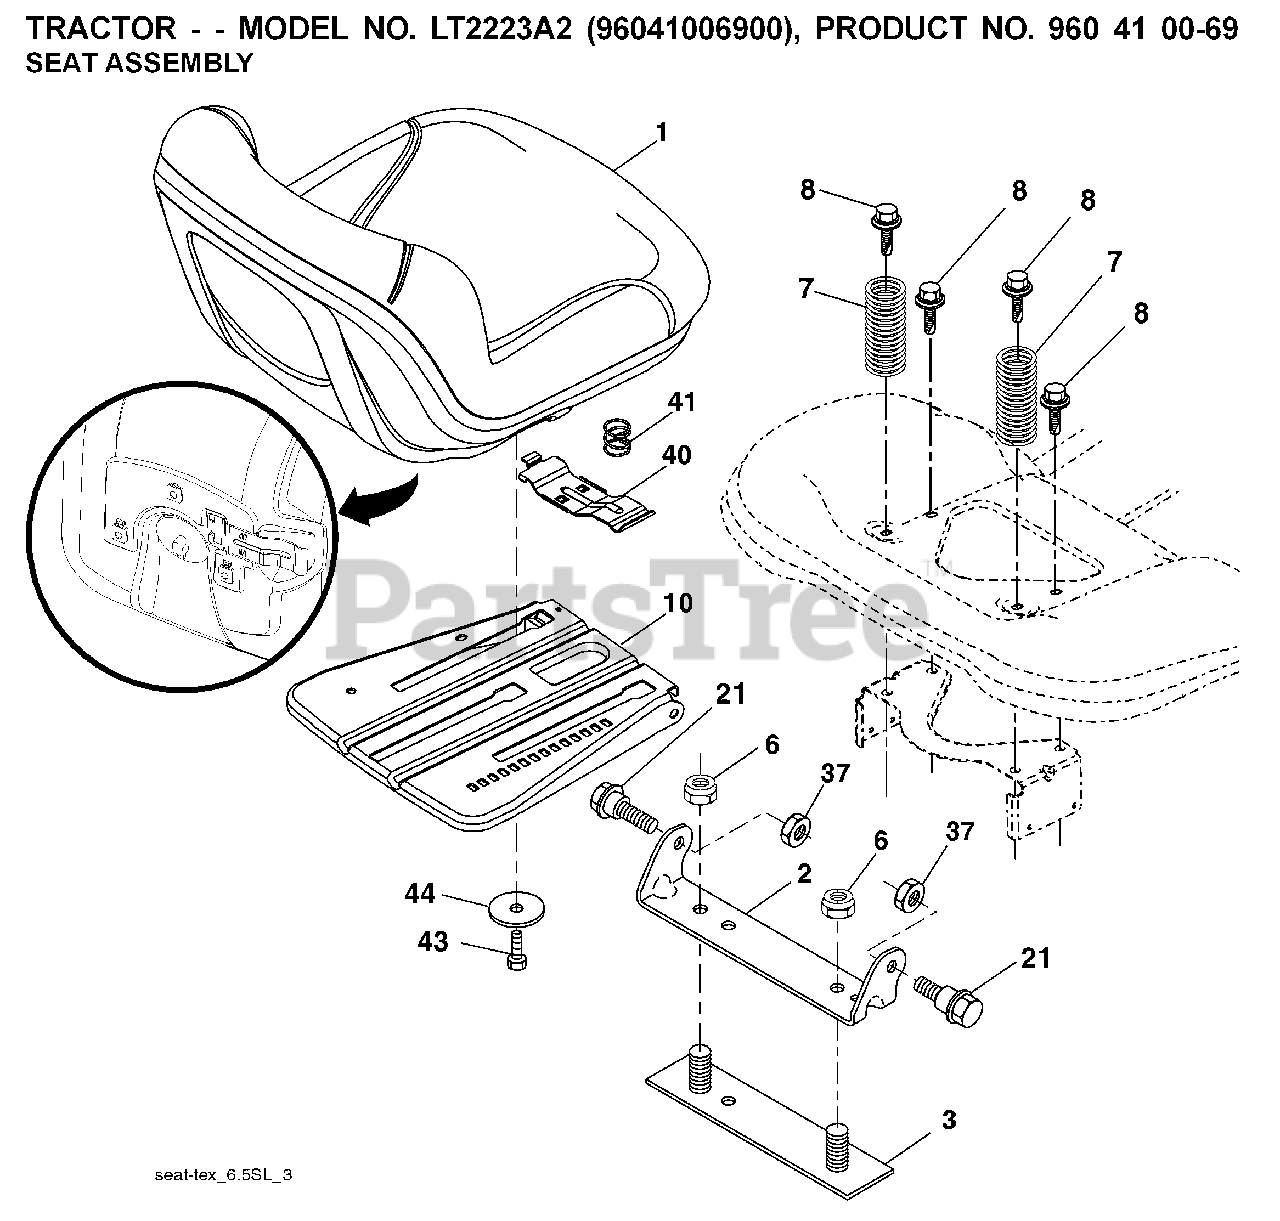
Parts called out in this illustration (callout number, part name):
1	SEAT.TG150.BLK.NLOGO.
2	BRKT.PIVOT.FENDER
6	NUT
7	SPRING COMPRESSION
8	BOLT, 5/16-18 X 1 3/4
10	PAN.ASM.SEAT.3PT
21	BOLT.SHOULDER.5/16-18
37	NUT.71038.31-18.HEX.NYLOCK
40	HANDLE.SLIDE.SEAT.TEX.BLACK
41	SPRING.LATCH.SEAT.TEX
44	WASHER 13/32 X 2-3/8 X 12GA
